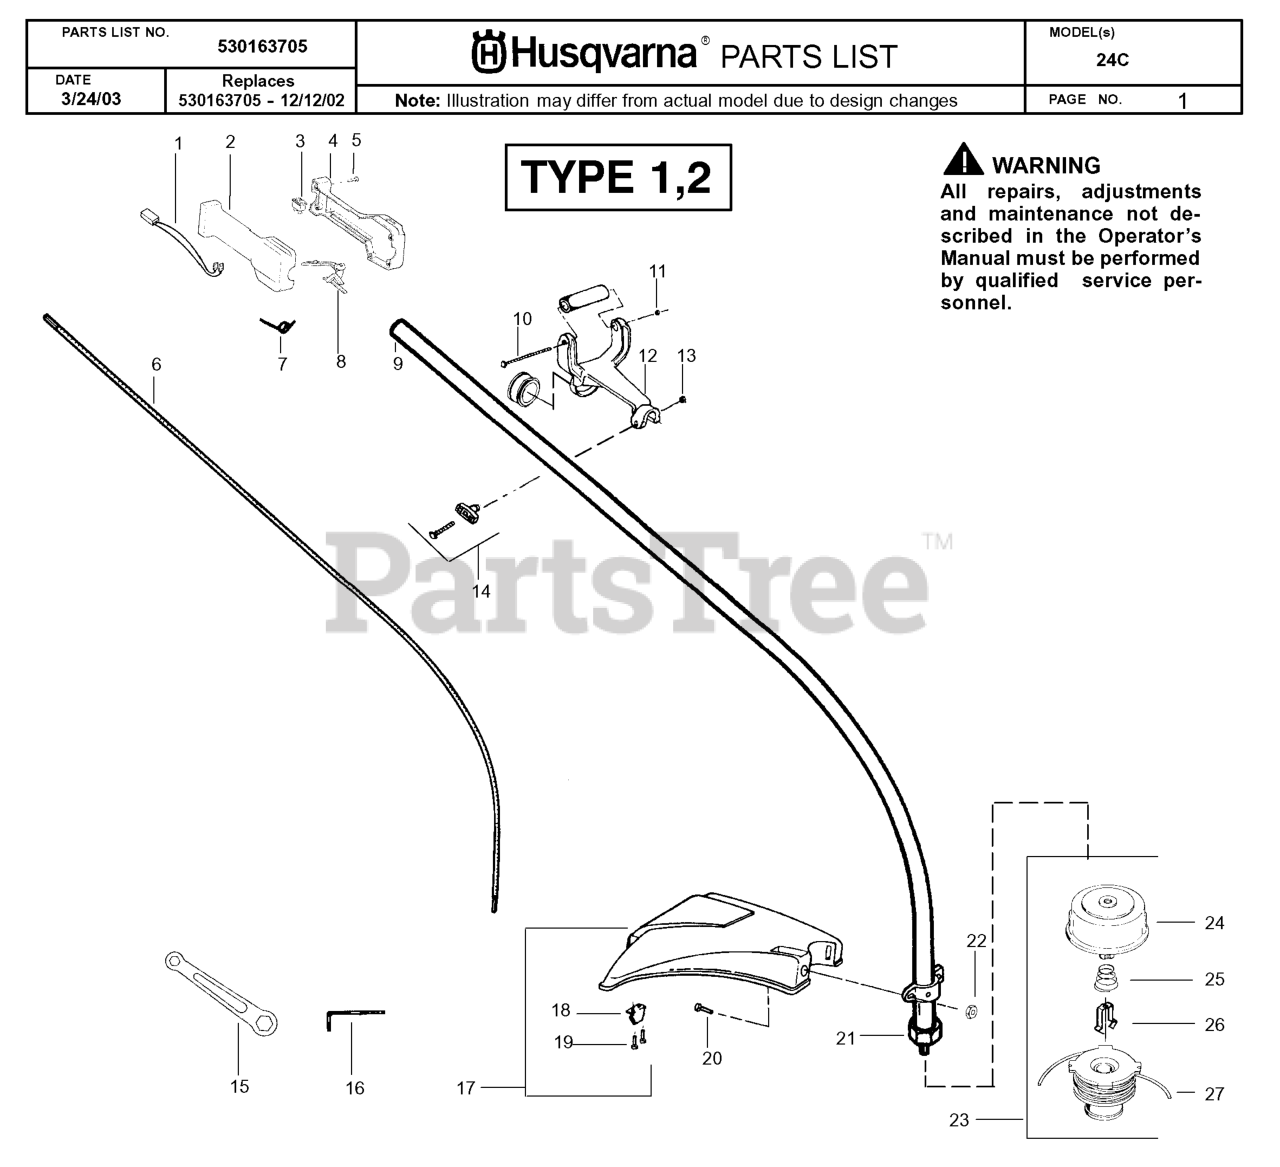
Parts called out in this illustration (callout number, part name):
2	THROTTLE HSG RH GRAY
4	THROTTLE HSG LEFT GRAY
5	SCREW-10-14 X 13/16 (PL
6	SHAFT-FLEX (48")
7	SPRING-LEVER RETURN
8	THROTTLE TRIGGER
9	ASSY D'SHAFT 51"
10	SCREW-12-24 X 4-11/16 P
11	NUT-12-24 (HEX)
12	ANTIVIBE HANDLE
14	HANDLE KIT
16	HEX WRENCH 5/32
18	Limiter - Line
20	BOLT, TYPE 2
21	DUST PROTECTION
24	KIT ASSY HUB W/ARBOR
27	WOUND SPOOL ASSY .080 x 2
530163627	MANUAL OPERATORS SCAN
530163628	MANUAL OPERATORS EURO
530163630	MANUAL OPERATORS EURO III
530163924	MANUAL OPERATORS N.AMERICAN
